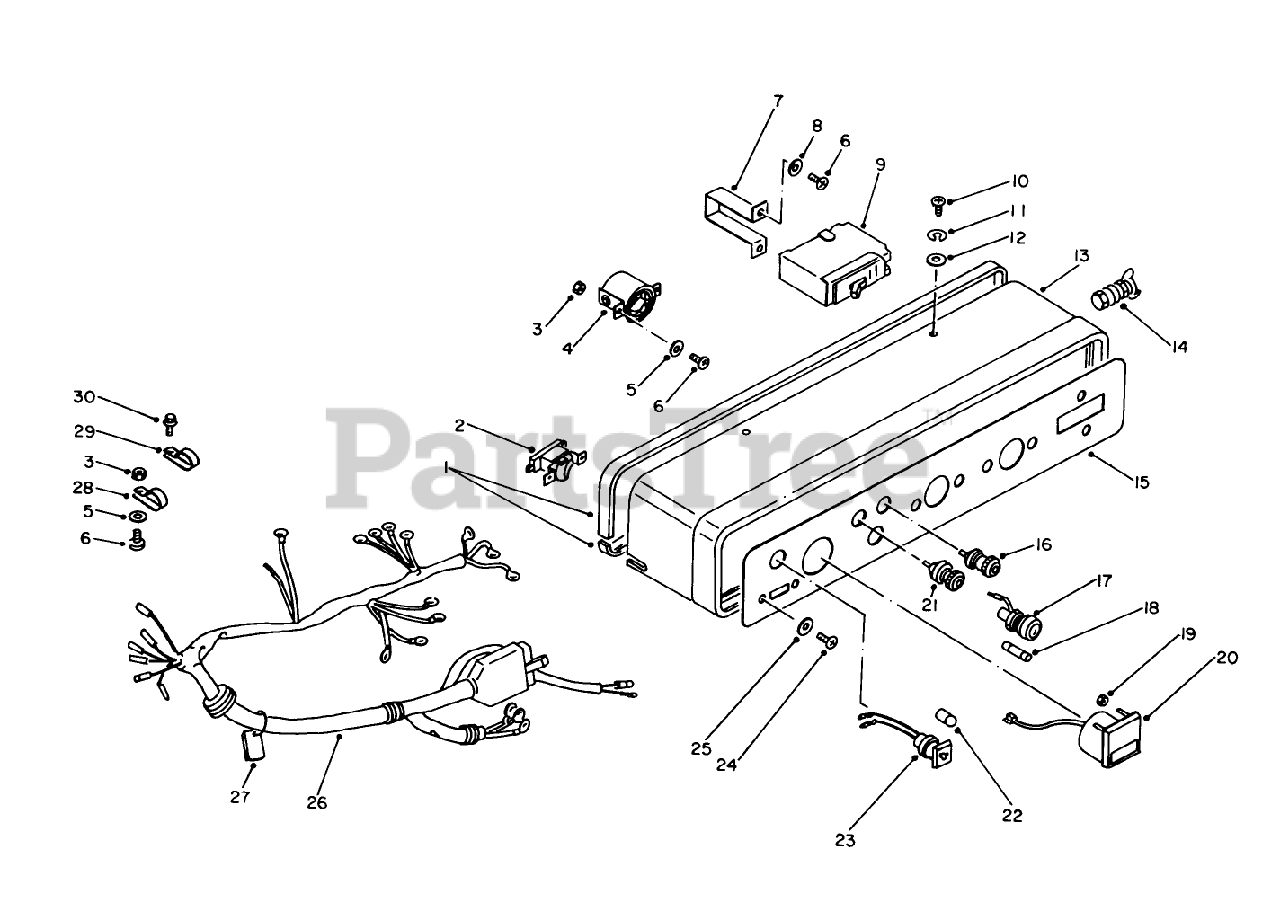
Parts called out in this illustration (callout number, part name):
2	Switch
4	RECEPTACLE
5	Washer
6	Screw
7	BREAKER HOLDER
8	Washer
9	CIRCUIT BREAKER
10	SCREW
11	Washer
12	WASHER
13	Panel-Control
14	GROUND TERMINAL
15	Plate-Panel
16	Terminal
17	Holder-Fuse (Incl. Ref. #18)
20	Meter-Voltage
21	TERMINAL (-)
23	Lamp (Incl.Ref.#19)
24	SCREW
25	Washer
26	Wiring Harness-Control
27	Fuse-Spare
28	Clamp
29	Clamp
30	SCREW-HHF
